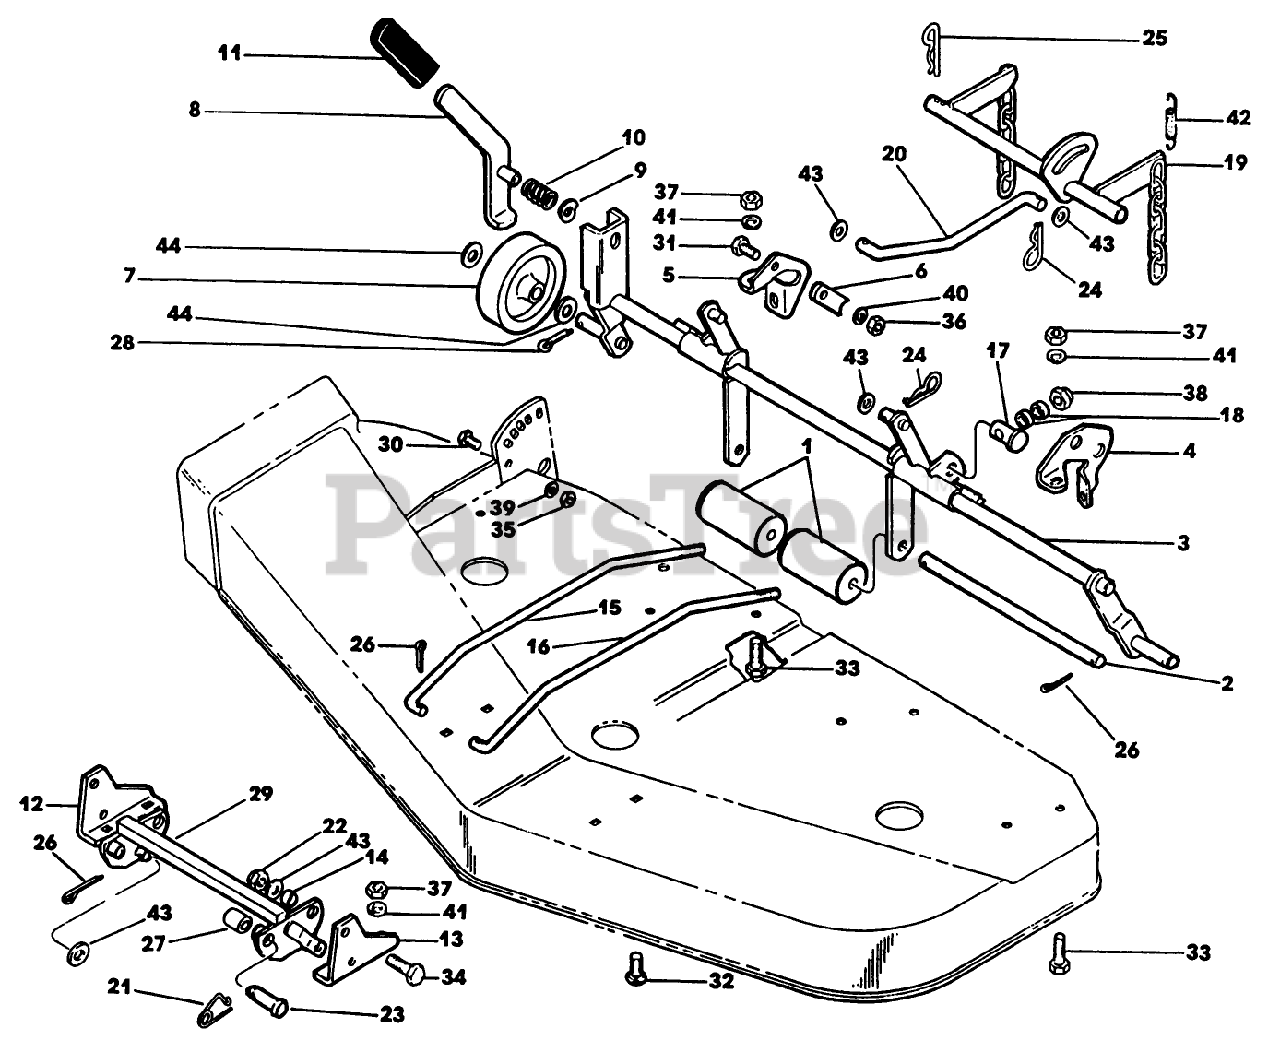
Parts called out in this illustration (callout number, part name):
1	ROLLER
2	SHAFT - ROLLER
7	WHEEL - MOWER
17	PIN - PIVOT
19	BELLCRANK ASSEMBLY *B
20	LINK - MOWER LIFT
21	PIN - SAFETY
22	NUT-LOCKING
23	PIN - CLEVIS
24	PIN-HAIR
27	SPACER
30	SCREW-HH
31	SCREW - HEX
35	NUT
36	NUT SS
37	NUT
38	NUT-HEX CONE LOK
41	WASHER
43	WASHER
